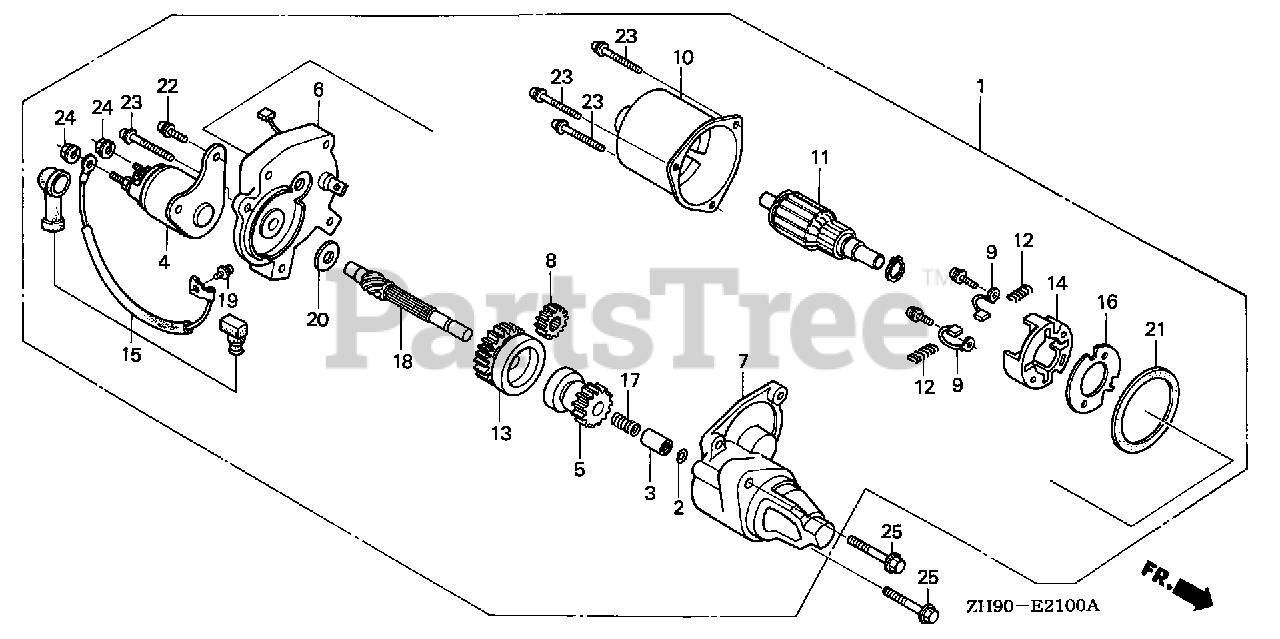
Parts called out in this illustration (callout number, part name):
1	STARTER MOTOR ASSY.
2	RING, SNAP
3	COLLAR, CLUTCH STOP
4	CONTACTOR ASSY.
5	CLUTCH, OVERRUNNING
6	BRACKET, CENTER
7	BRACKET, FR.
8	GEAR, DRIVE PINION
12	SPRING, BRUSH RETURN
13	GEAR, REDUCTION
14	HOLDER, BRUSH
15	WIRE, WATER COVER
19	SCREW-WASHER (4X6)
20	WASHER, SK
22	BOLT-WASHER (5X14)
23	SCREW-WASHER (5X32)
24	NUT-WASHER (6MM)
25	BOLT, FLANGE (8X40)
